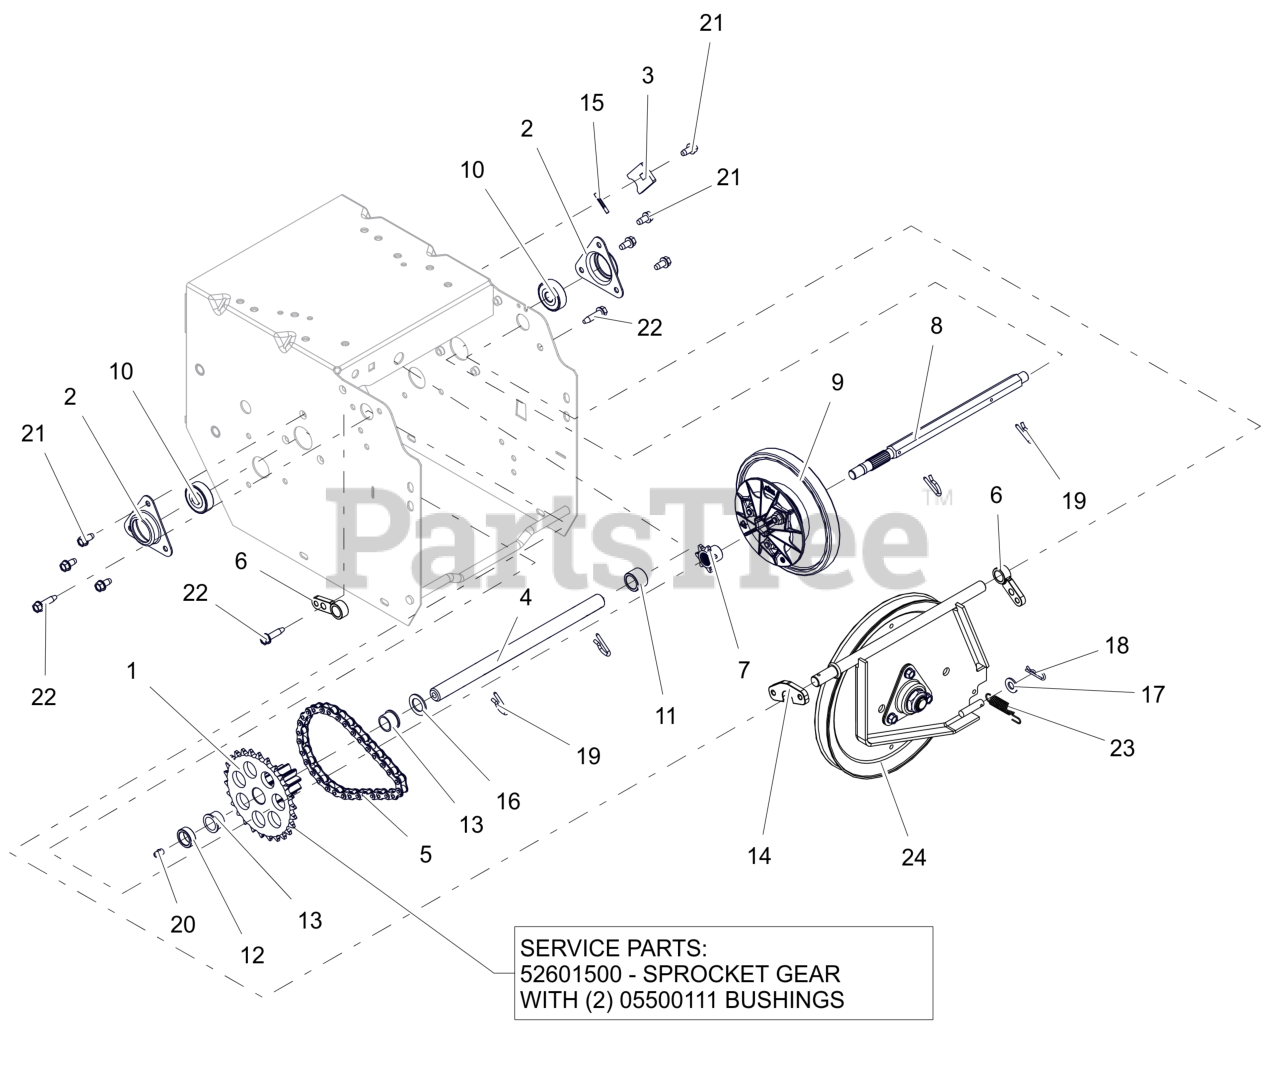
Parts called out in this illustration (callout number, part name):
1	PINION & SPROCKET
1	PINION & SPROCKET W/BUSHINGS
2	FLANGE, BEARING
3	TAB, ANTI ROTATION
4	SHAFT, PINION
5	CHAIN - #41, 32 PITCHES
6	SUPPORT BUSHING, SWING GATE
7	SPROCKET, PINION 7T W/SPLINE
8	SHAFT, HEX W/SPLINE
9	DISC, FRICTION DRIVE-ASSEMBLY
10	BRG-BALL .437X1.375X.437
11	SPACER, .635X.880X.611
12	BSHG-SLV, .635X.880X.305
13	BSHG-FLG .625X.750X.500X.875
14	SPACER, SWING GATE
15	@PIN-GRV .125X1.00 TP E ALLOY
16	WSHR, FLT .630X1.005X.062 ZCC
17	WSHR,FLT .344X.688X.065 ZCC
18	PIN, HAIR #213 .08X1.19 ZCC
19	PIN, SPRING CLIP
20	ZERK,FITTING .25X.125 DRIVE IN
21	SCR-TAP .25-20X.50 HWH ZCC
22	SCR, TAP .25-20X1.00 TT2000 ZCC
23	SPRING, EXT. .043X.438X1.64
24	PLATE, SWING - ASSEMBLY
